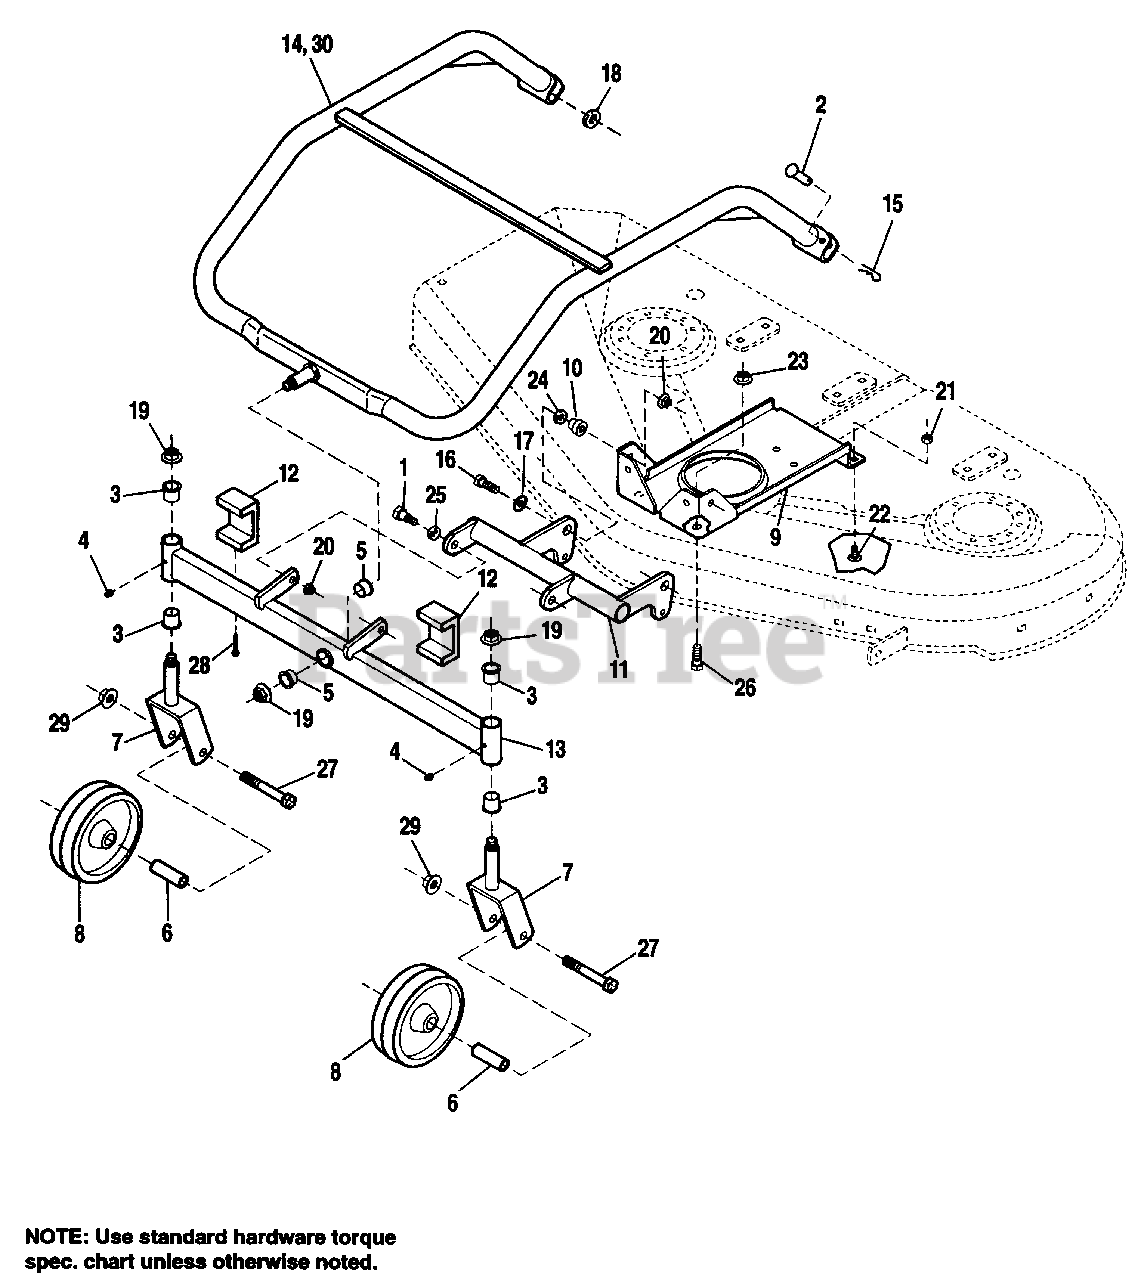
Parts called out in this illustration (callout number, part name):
1	BOLT, Shoulder, 3/8-16 X 1.34
2	PIN, Hitch
4	FITTING, Grease, 1/4
9	SUPPORT ASSY.
11	ROCKER ARM ASSY.
12	BEARING, Block
13	AXLE ASSY., Mower (Incl. Ref. Nos. 12 & 28)
14	MOWER ARM ASSY., 42", Orange
15	PIN, Hair Pin
16	CAPSCREW, Hex, 3/8-16 x 1-1/2
17	WASHER, 3/8
18	WASHER, 5/8
19	NUT, Centerlock, 1/2-13
20	NUT, Hex, Whizlock, 3/8-16
21	NUT, Hex, Whizlock, 5/16-18
22	CARRIAGE BOLT, 5/16-18 x 3/4
23	NUT, Whizlock, 7/16-14
24	WASHER, Plain
25	WASHER, Plain
26	CAPSCREW, Whizlock, 7/16-14 x 1
27	CAPSCREW, Hex, 1/2-13 x 3-1/2
28	SCREW, Self-Tapping
29	NUT, ESNA, Lock, 1/2-13 (Thin)
30	MOWER ARM ASSY., Black
